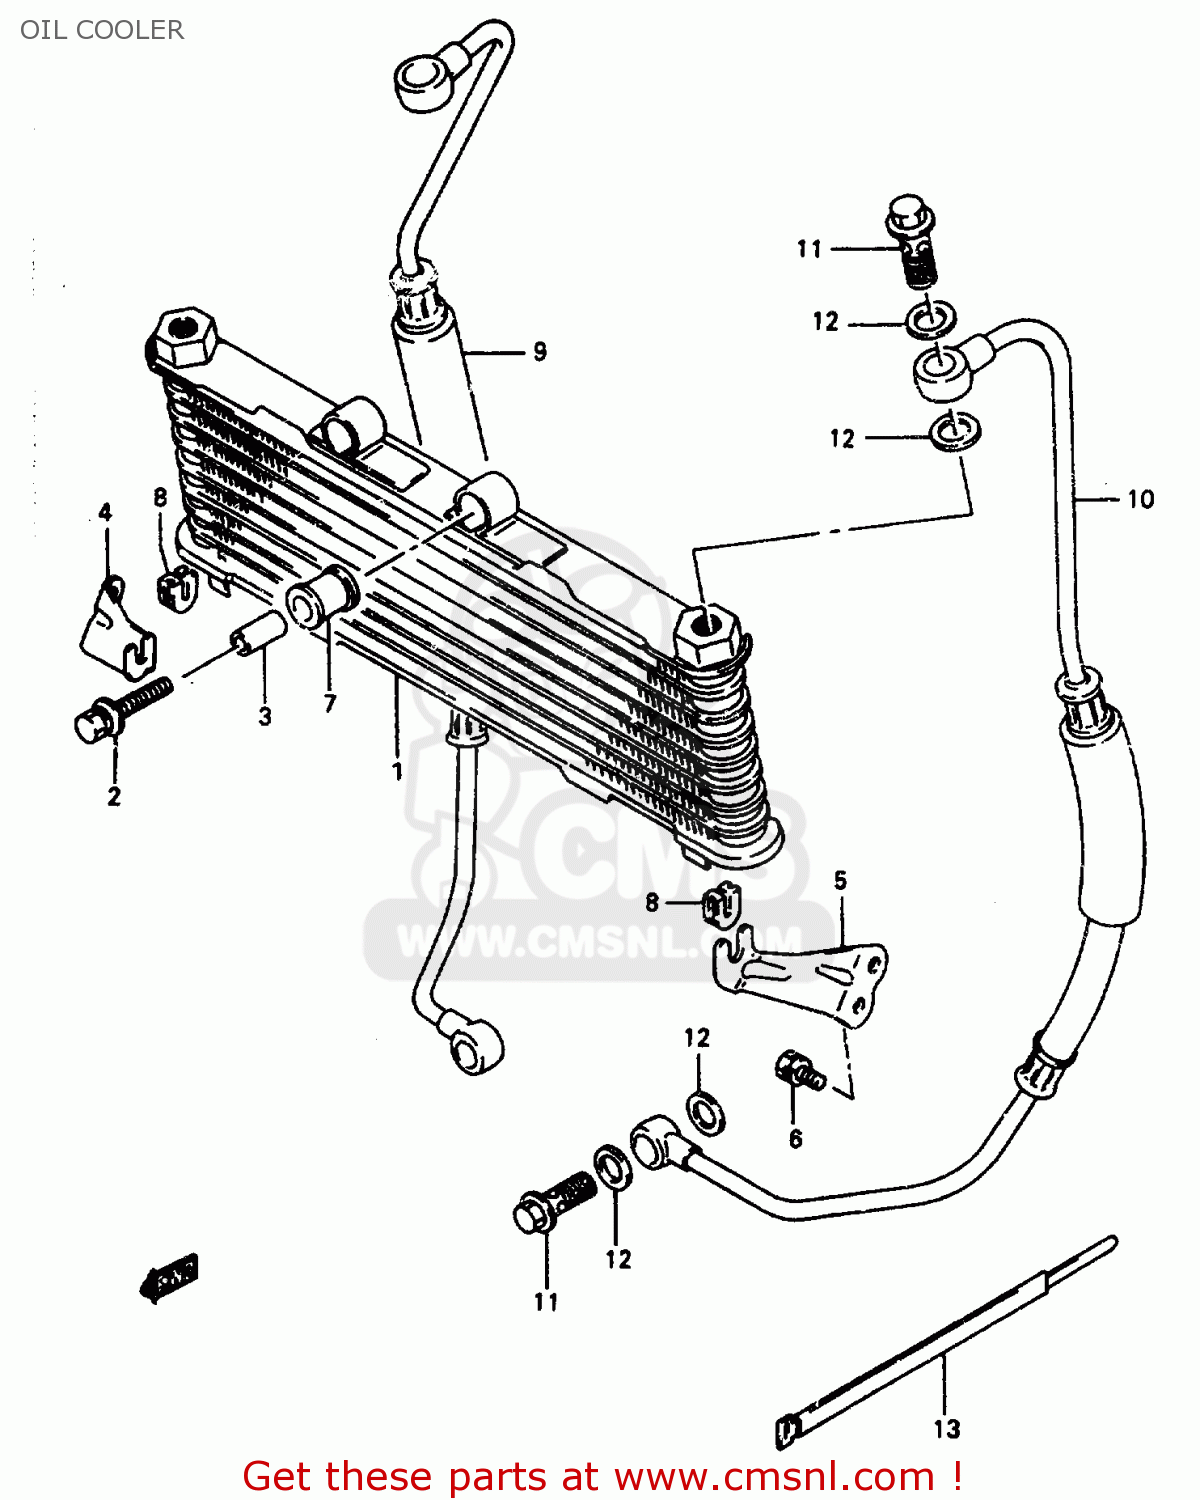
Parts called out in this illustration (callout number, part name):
1	COOLER ASSEMBLY,OIL
2	BOLT(8X40)
3	SPACER(8.5X12X25)
4	BRACKET,OIL COOLER,R
5	BRACKET,OIL COOLER,L
6	BOLT
7	CUSHION,OIL COOLER NO.1
8	CUSHION,OIL COOLER NO.2
9	HOSE,OIL COOLER,RIGHT
10	HOSE,OIL COOLER,LEFT
11	BOLT UNION
12	GASKET(16X22X2) (NAS)
13	CLAMP(L:235)
